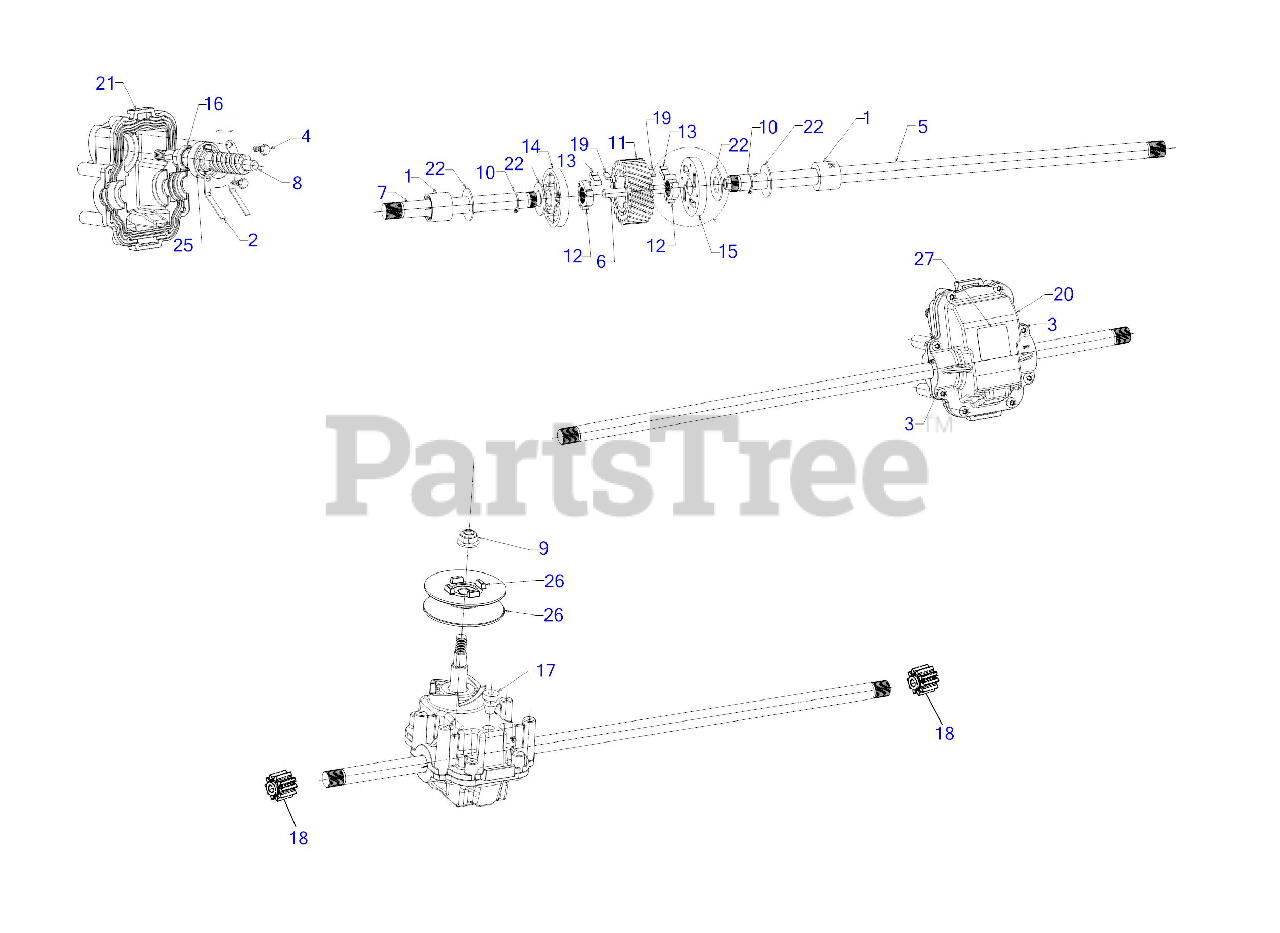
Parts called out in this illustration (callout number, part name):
1	#N/A
2	#N/A
3	SCREW .159 x .610
4	SCREW .159 x .43
5	#N/A
6	#N/A
7	#N/A
8	#N/A
9	FLANGE LOCK NUT 5/16-18
10	SNAP RING FOR .500
11	#N/A
12	#N/A
13	#N/A
14	#N/A
15	#N/A
17	RUBBER PLUG
18	SPUR GEAR 9T
19	#N/A
20	#N/A
21	#N/A
22	FLAT WASHER .508X1.000X.040
25	BALL BEARING
26	HALF PULLEY 2.5 OD
27	LABEL
